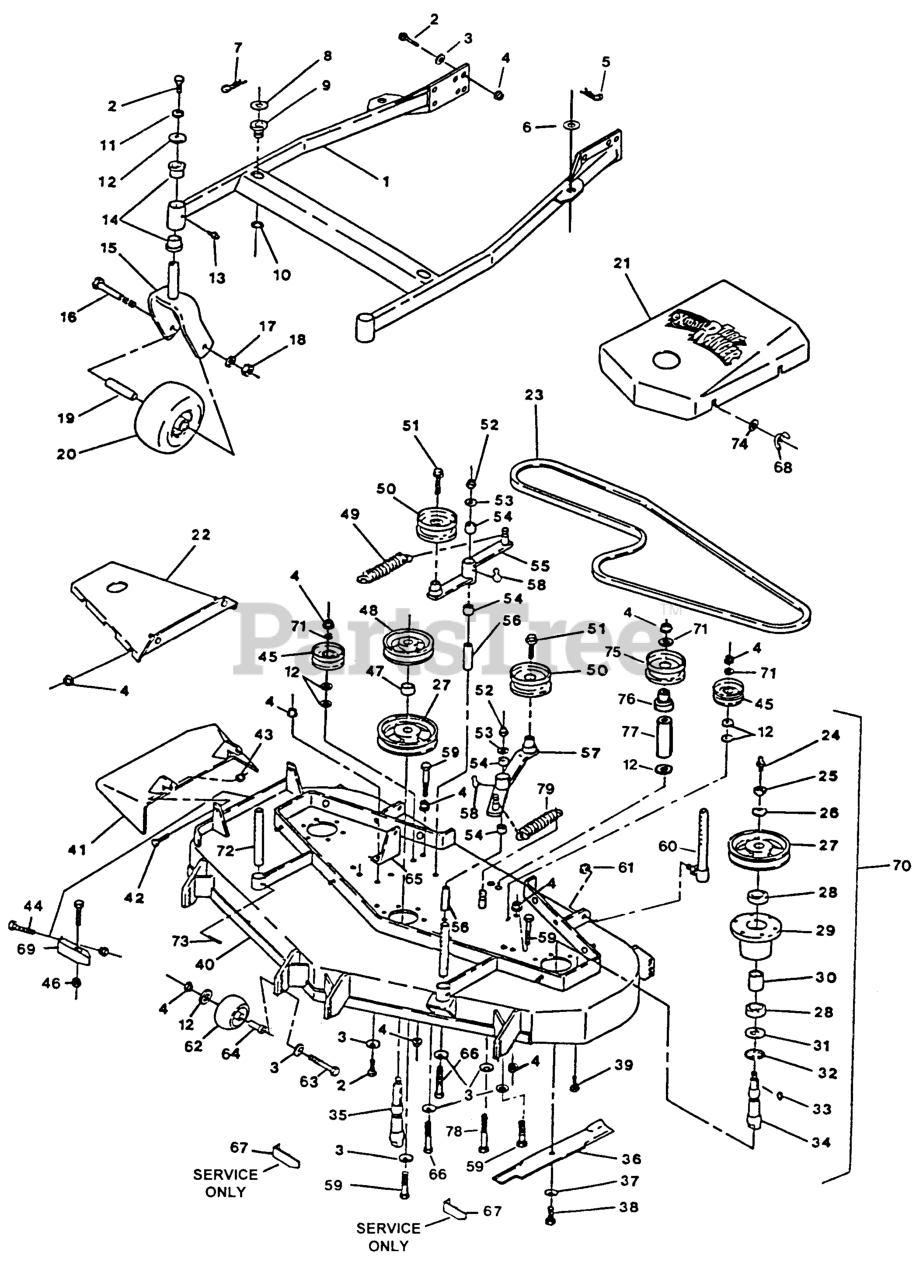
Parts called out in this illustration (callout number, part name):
5	PIN,HAIR COTTER
8	WASHER-FLAT
9	BUSHING-DECK
12	WASHER
14	BEARING-FLANGED
23	BELT,BLADE DRIVE
26	WASHER-SPRING
27	SHEAVE,BLADE DRIVE
30	SPACER,BEARING
31	SEAL,MECHANICAL DUST
32	RING,SNAP WLDS N5000-244
34	SPINDLE-OUTER BLADE
35	SPINDLE-CENTER BLADE
37	WASHER-SPRING
39	SCRW,TPTTE HH
41	WLD,CHUTE DISCHARGE
45	IDLER,PULLEY
47	SPACER-TUBE
48	SHEAVE,MOWER DRIVE
49	SPRING-EXTENSION
50	IDLER,PULLEY
54	SLEEVE-BEARING
55	ASM,IDLER ARM
56	BUSHING-PIVOT, IDLER
57	ASM,IDLER ARM
62	ROLLER-SCALP, ANTI
64	BUSHING-ROLLER
65	BRACKET,SPRING ANCHOR
66	SCREW-HH
68	NUT-WING
69	WLD,BAFFLE DISCHARGE
72	ROD,DECK SUPPORT
75	PULLEY-IDLER
76	BUSHING,IDLER
77	SPACER-FENDER
79	SPRING-EXTENSION
